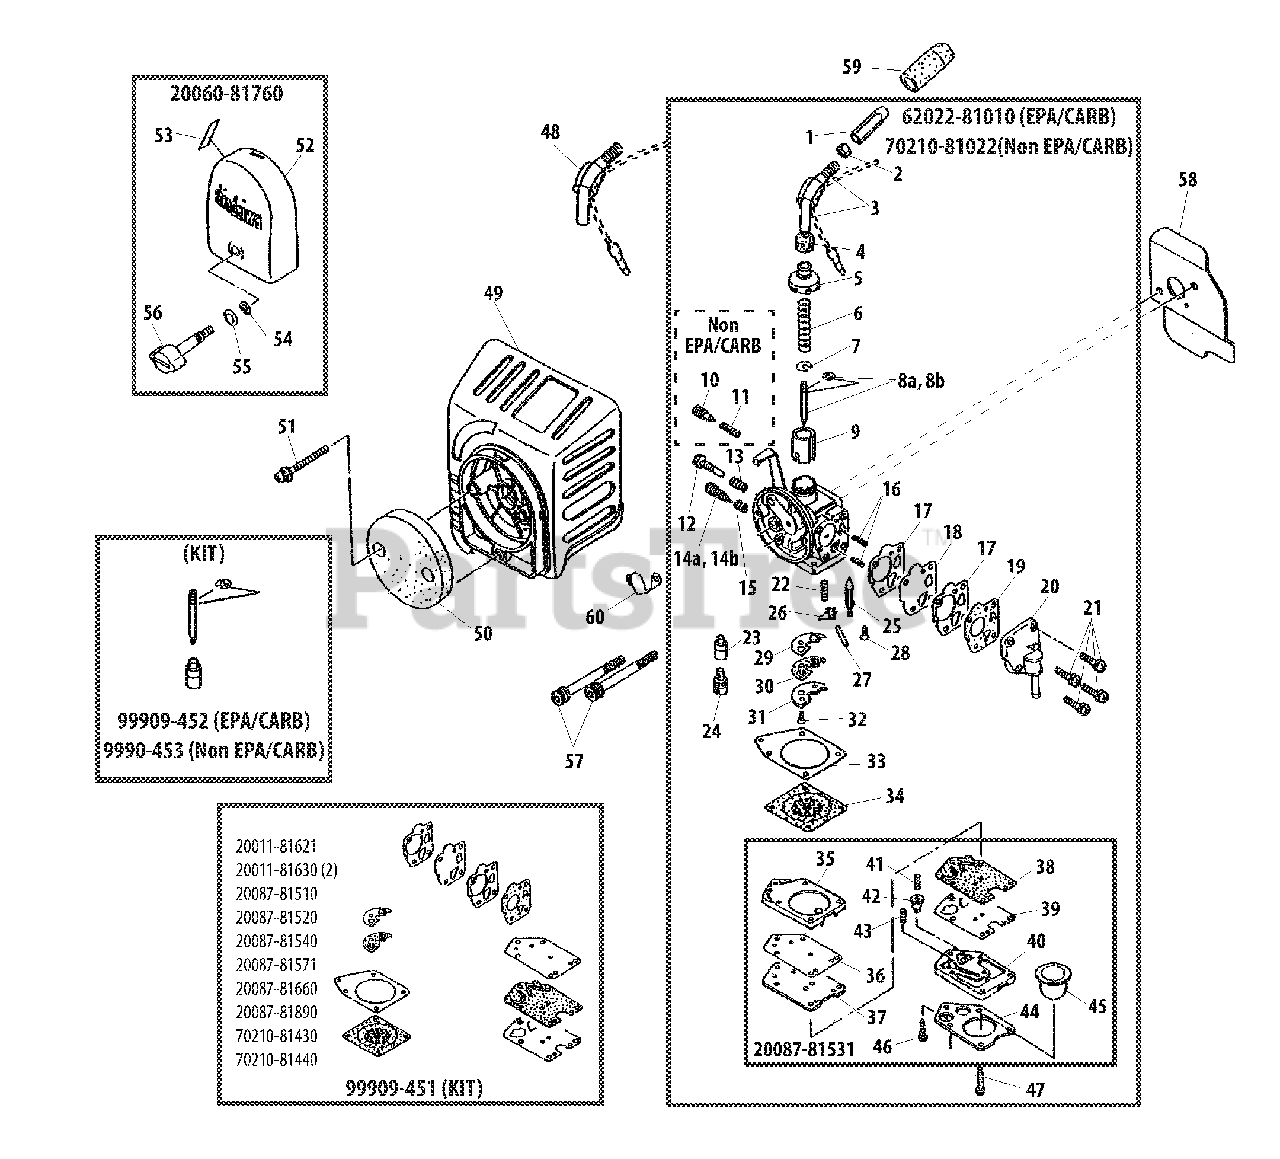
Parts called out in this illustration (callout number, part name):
1	NUT, CABLE ADJUST
2	LOCKNUT
3	GUIDE, CABLE
4	GROMMET
5	CAP, CARBURETOR
6	SPRING, THROTTLE
7	RETAINER
8A	NEEDLE, JET
8B	NEEDLE, JET
9	VALVE, THROTTLE
10	SCREW, SLOW AIR
11	SPRING
12	SCREW, IDLE ADJUST
13	SPRING
14A	SCREW, IDLE ADJUST
14B	SCREW, IDLE ADJUST
15	SCREW, IDLE ADJUST
16	SPRING
17	GASKET, METERING
18	DIAPHRAGM, METERING
19	VALVE, PUMP
20	BODY, PUMP
21	SCREW
22	SPRING
23	NEEDLE, JET
24	HOLDER, JET
25	VALVE, INLET NEEDLE
26	LEVER, METERING
27	PIN, METERING LEVER
28	SCREW, METERING LEVER PIN
29	GASKET
30	VALVE, CHECK
31	PLATE
32	SCREW, METERING LEVER PIN
33	GASKET, METERING
34	DIAPHRAGM, METERING
35	BASE, PURGE
36	GASKET
37	PLATE, PUMP
38	DIAPHRAGM
39	GASKET
40	COVER, PUMP
41	SPRING, RETURN
42	VALVE
43	SPRING
44	PLATE
45	BULB, PURGE
46	SCREW
47	SCREW
48	TUBE
49	CASE, AIR FILTER
50	FILTER, AIR
51	SCREW - 4X25
52	COVER, AIR FILTER
53	LABEL - CHOKE
54	O-RING
55	WASHER - CONICAL
56	KNOB
57	SCREW - 5X50
58	SHIELD, INTAKE
59	CAP, DUST
60	BRACKET
20060-81760	AIR FILTER COVER ASSY
20087-81531	PRIMER PUMP ASSY
62022-81010	CARBURETOR
70210-81022	CARBURETOR
99909-451	DIAPHRAGM/GASKET KIT
99909-452	NEEDLE/JET KIT
99909-453	NEEDLE/JET KIT
